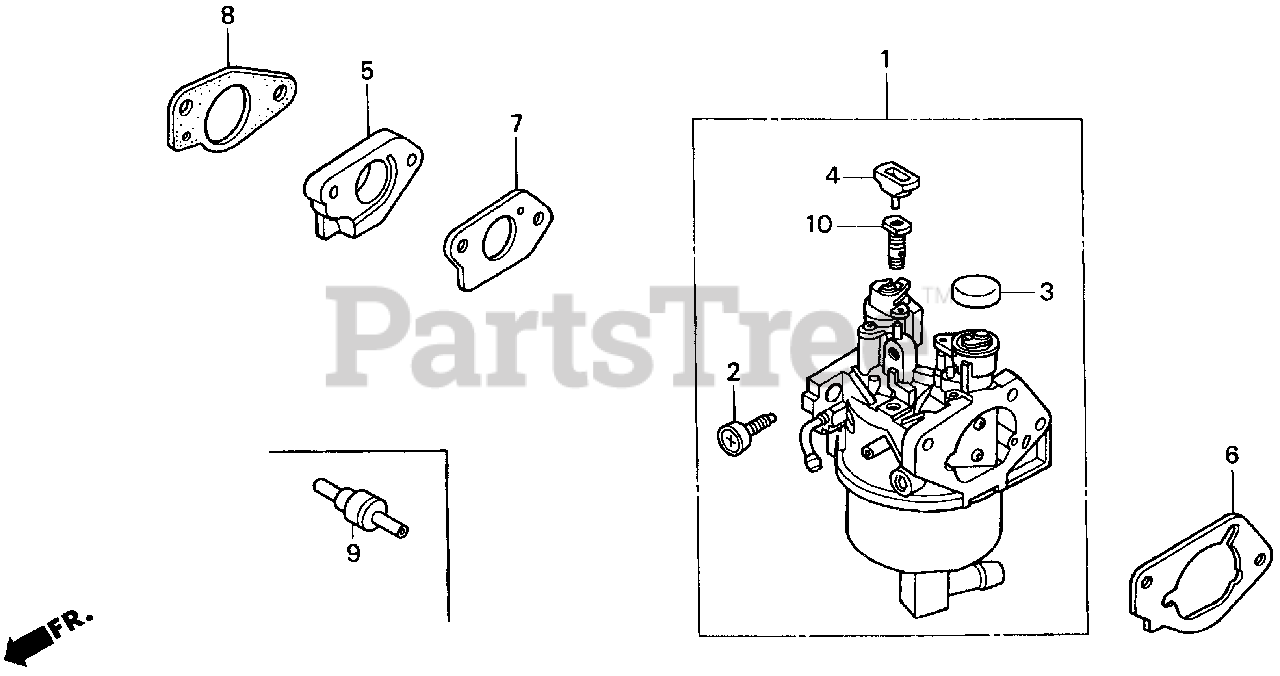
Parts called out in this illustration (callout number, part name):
1	CARBURETOR ASSY. (BEL7A B)
2	SCREW, THROTTLE STOP
3	CAP, CHOKE LEVER DUST
4	COLLAR, SET
5	INSULATOR, CARBURETOR
6	SPACER COMP., CARBURETOR
7	GASKET, CARBURETOR
8	GASKET, INSULATOR
9	VALVE, DASHPOT CHECK
10	JET, PILOT (#45)
